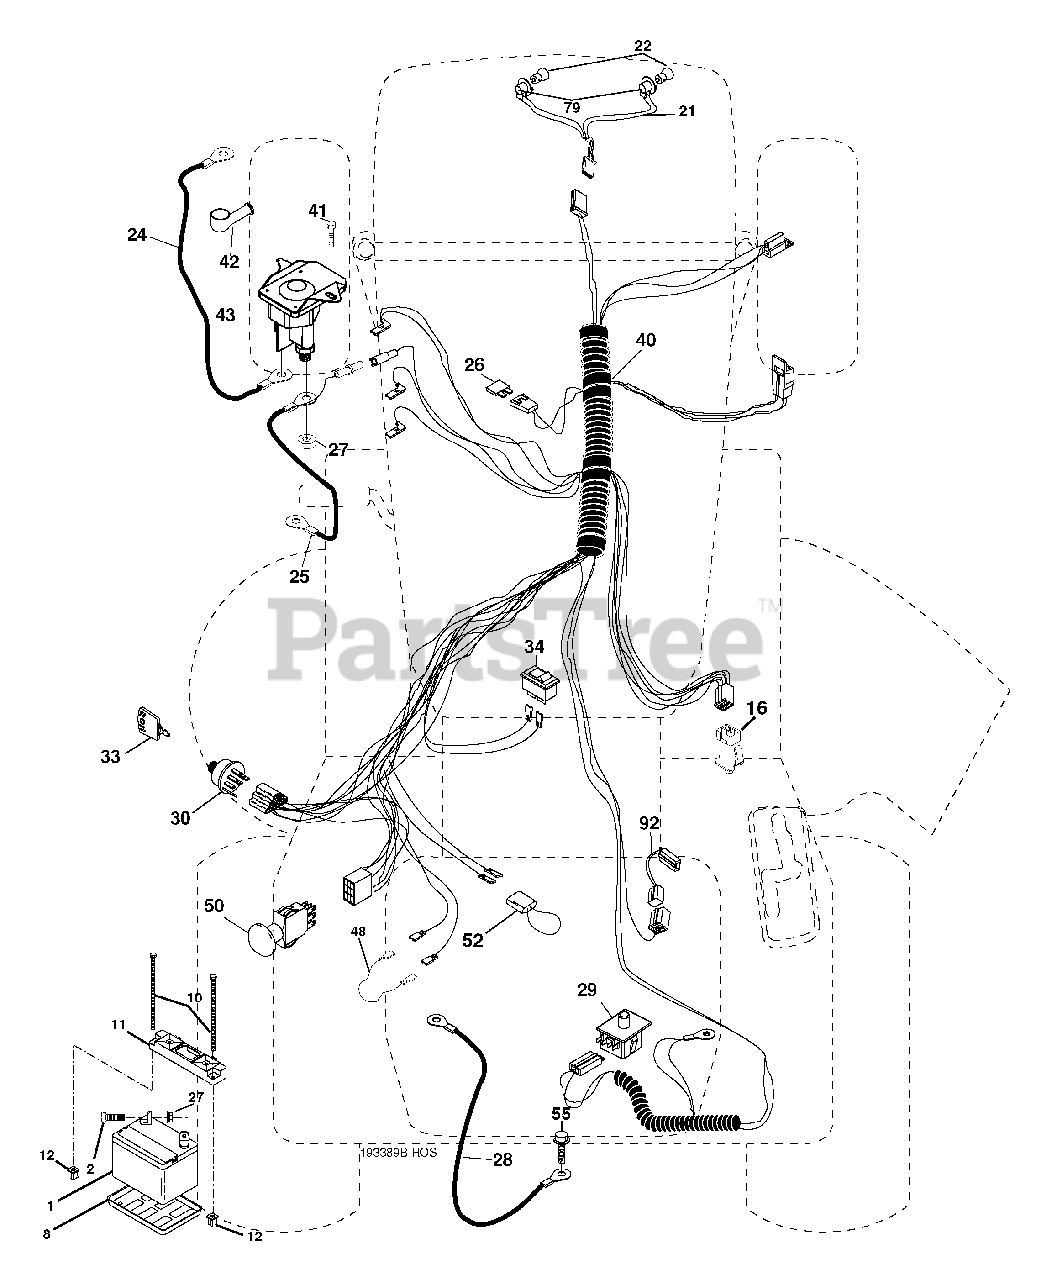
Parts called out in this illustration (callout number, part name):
1	Battery
2	Bolt Hex Hd 1/4-20 unc x 3/4
8	Tray Battery
10	Bolt Battery Front 1/4-20 x 7.5
11	Holddown Battery
12	Nut Push Nylon 1/4
16	Switch Interlock
21	Harness Socket Light
22	Bulb, Light # 1156
24	Cable Battery
25	Cable Battery 6 Ga. Red w/16 wire
26	Fuse
27	Nut Keps Hex 1/4-20 unc
28	Cable Ground 21" Blk 6 Ga.
29	Switch Seat
30	Switch Ign
33	Key Ign Molded Generic
34	Switch Light/Reset
40	Harness Ign
41	Bolt Fin Hex 1/4-20 unc x 1/2
42	Cover Terminal Red
43	Solenoid
45	Ammeter Rectangular
50	Switch PTO
52	Protection Loop
55	Screw Thdrol 5/16-18 x 1/2
79	Socket Asm Bulb Twistlock
92	Harness Pigtail Trans.
